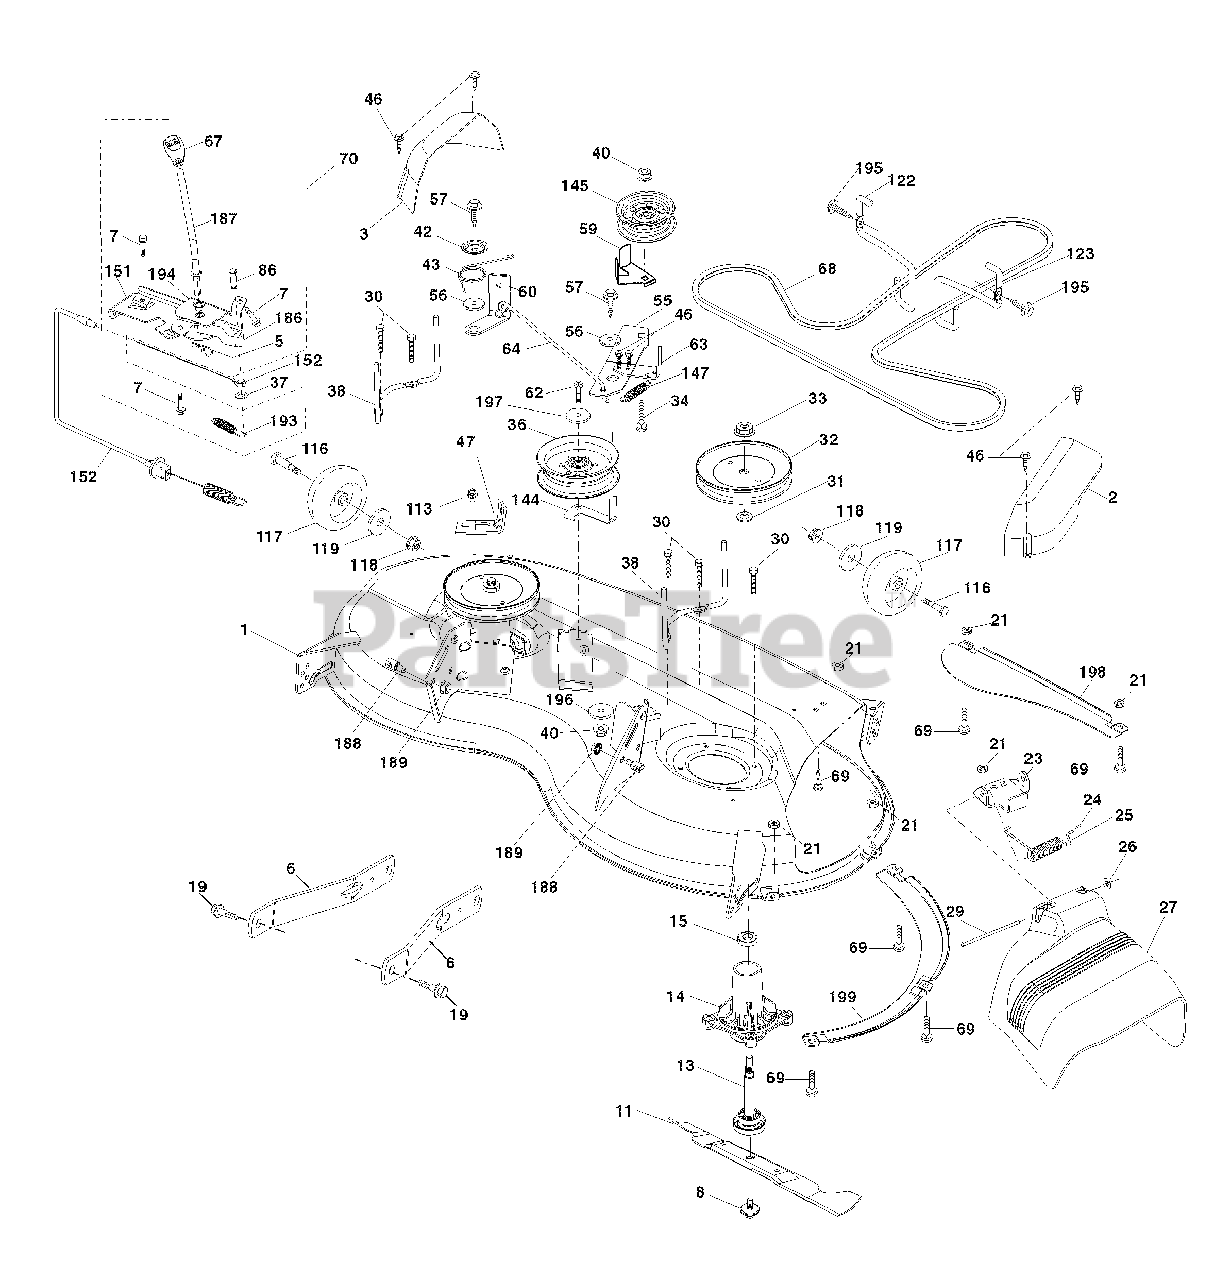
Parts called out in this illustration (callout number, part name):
1	Mower Housing
2	Cover Mandrel RH
3	Cover Mandrel LH
5	Retainer Spring
6	Arm Suspension
7	Screw 10 x 3/4 Single Hex
8	Bolt/Washer asm 7/16-20 unf
11	Blade Mower
13	Shaft Assembly, Mandrel
14	Housing, Mandrel
15	Bearing, Ball, Mandrel
19	Bolt, Shoulder
21	Nut
23	Bracket, Deflector
24	Cap, Sleeve
25	Spring, Torsion, Deflector
27	Shield, Deflector
29	Rod, Hinge
30	Screw Thdrol Rolling Wsh Hd
31	Washer, Spacer
32	Pulley, Mandrel
33	Nut, Toplock, Flanged
34	Bolt Carr Sh. 3/8-16 x 1-1/2 Gr. 5
36	Pulley, Idler, Flat
37	Washer 13/32 x 13/16 x 16 Ga.
38	Keeper Belt LH Mandrel
40	Nut, Lock Flg. 3/8-16 unc
42	Spring Trosion Brake
43	Spring Torsion Retainer
47	Bracket Clutch Cable
55	Arm, Idler
56	Spacer, Retainer
57	Screw Hexwsh Thd 3/8-16 x 1
59	Guard, Tuv Idler
60	Arm Brake Mower LH
62	Bolt 3/8-16 UNC x 2-1/4 Gr. 5
63	Arm Brake Mower
64	Linkage Brake
67	Handle, Clutch Cable
68	V-Belt
69	Bolt
70	Clutch Asm. Cable
86	Pin Attachment Cable
113	Screw 5/16-18
116	Bolt, Shoulder
117	Wheel, Gauge
119	Washer 13/32 x 1-1/4 x 12 Ga.
122	Keeper Belt Eng. LH
123	Keeper Belt Eng. RH
144	Keeper Belt
145	Pulley Idler
147	Spring Return
149	Retainer Spring Yellow
151	Bracket Mount
152	Cable Clutch Manual w/Spr.
186	Arm Acutator CL Cable
187	Lever Control CL Cable
188	Stud Fastener
189	Nut Lock Hex Flange
193	Spring Plunger Actuator
194	Bearing Control Lever Clutch
195	Screw 3/8-16 x 3/4
196	Washer 13/32 x 1 x 1/2 11 Ga.
197	Washer 13/32 x 13/16 x 12 Ga.
198	Baffle Center Front
199	Baffle Front RH
199	Mandrel Assembly
199	Replacement Mower, Complete
